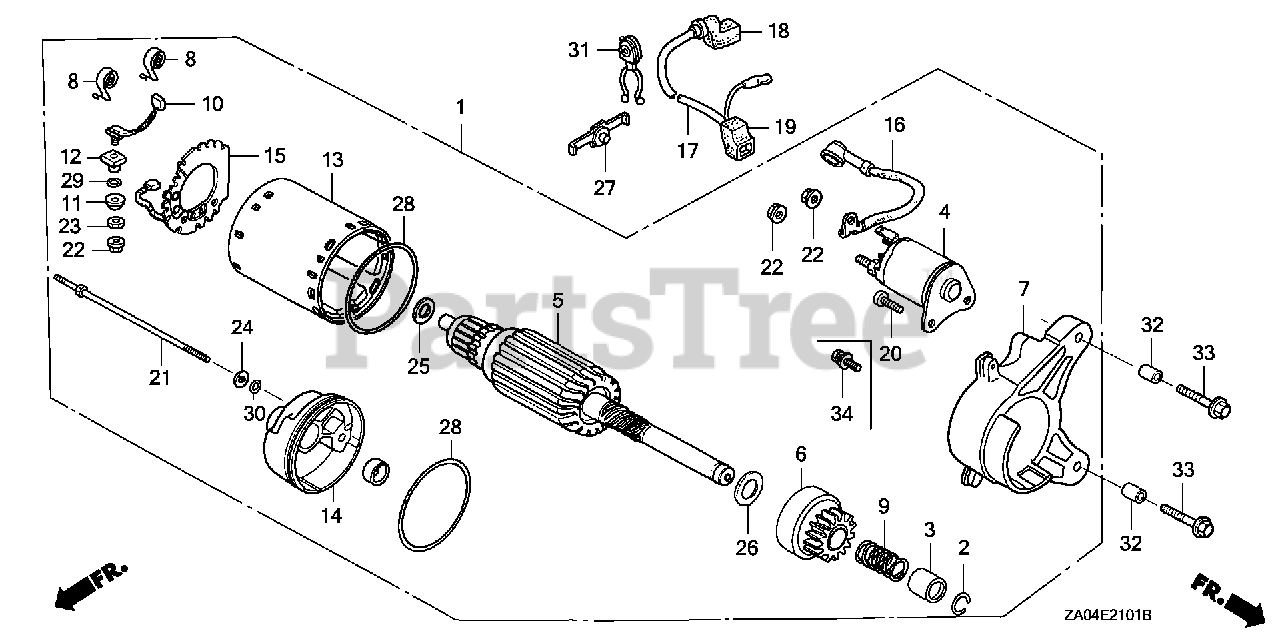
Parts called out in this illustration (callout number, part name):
1	MOTOR ASSY., STARTER
2	RING, SNAP
3	COLLAR, CLUTCH
4	CONTACTOR ASSY.
5	ARMATURE
6	CLUTCH, OVERRUNNING
7	HOUSING, DRIVE SIDE
8	SPRING, BRUSH
9	SPRING
10	BRUSH
11	BUSHING, INSULATION
12	BUSHING, INSULATION
13	YOKE
14	FRAME, STARTER END
15	PLATE, BRUSH HOLDER
16	WIRE, WATER COVER
17	CABLE, STARTING
18	COVER, BATTERY
19	COVER B, MAGNETIC SWITCH (Honda Code 1059369). (NOT AVAILABLE)
20	SCREW-WASHER (5X14)
21	BOLT, THROUGH
22	NUT
23	NUT
25	WASHER
26	WASHER
27	CLIP, WIRE HARNESS (Honda Code 1685387). (BLUE)(HARNESS TAPING)
29	O-RING
30	O-RING
31	CLAMP, WIRE HARNESS
32	PIN A, DOWEL (10X16)
33	BOLT, FLANGE (8X40)
